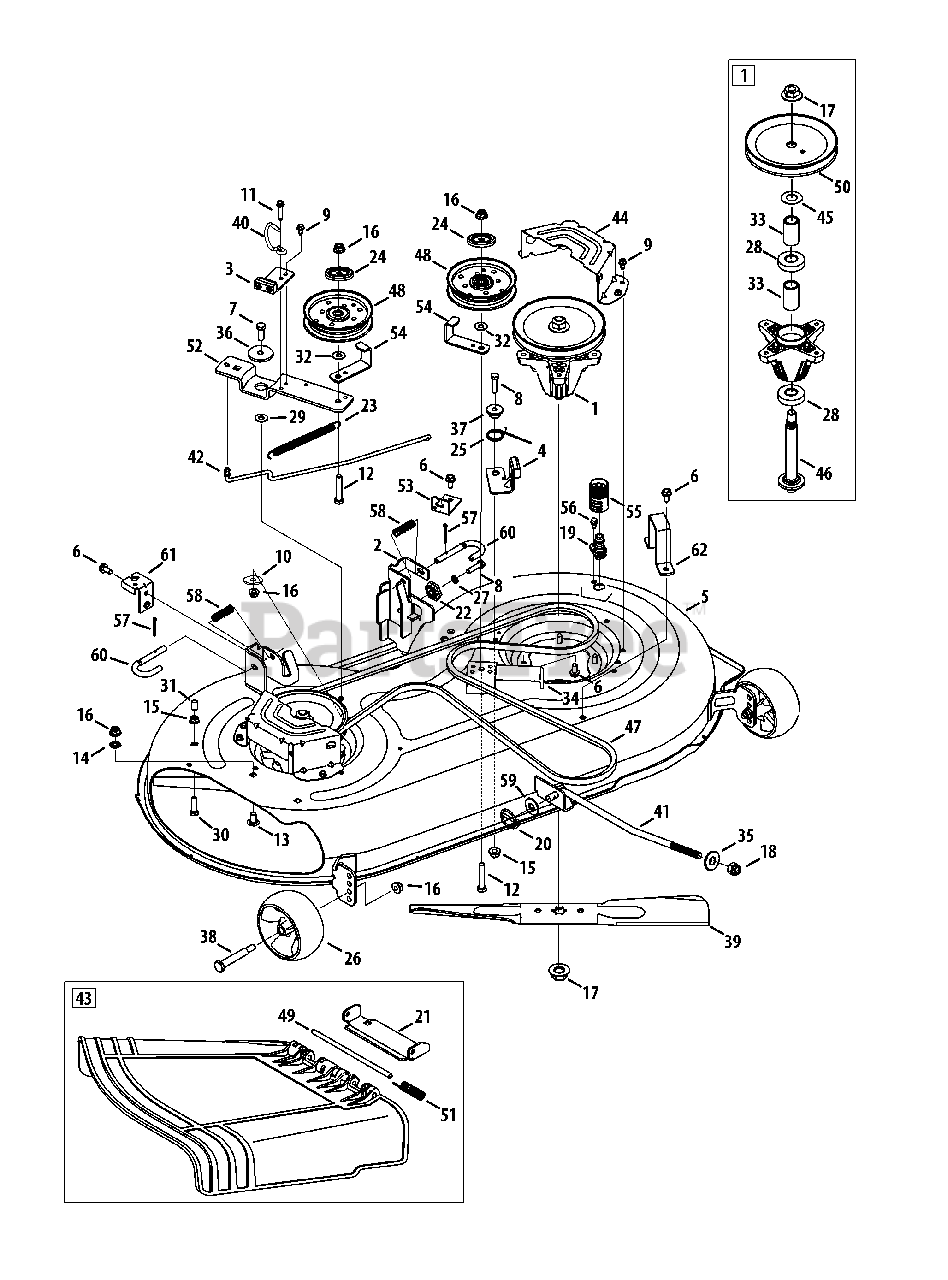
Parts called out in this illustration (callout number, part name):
1	Spindle Ass’y, Pulley, 6.3 Dia
2	Bracket Ass’y, Deck, Hanger LH
3	Brake Ass’y, Deck, 42/46
4	Brake Ass’y, Deck
5	Deck Ass’y, Offset, 42" W/O wheel
6	Screw, Self-tapping, 5/16-18, .750
7	Hex Screw, 3/8-16, 1.25, Gr5, Std
8	Hex Screw, 5/16-18, 1.25, Gr5, Std
9	Screw, Self-tapping, 1/4-20, 0.500
10	Flat Washer, .406 x 1.500 x .105
11	Screw, Self-tapping, 1/4-20, .750
12	Hex Screw, 3/8-16, 2.00, Gr5, Std
13	Bolt, Carriage, 3/8-16, 0.75, Gr1
14	Nut, Push, 3/8
15	Nut, Flange Lock, 5/16-18, Grf
16	Nut, Flange Lock, 3/8-16, Grf
17	Nut, Flange, 5/8-18
18	Nut, Lock, 1/2-13
19	Deck Wash Nozzle
20	Lynch Pin, .1875
21	Chute Bracket
22	Gear, Deck, Adjustment
23	Spring, Extension, .62 Dia x 6.12
24	Pulley Cap
25	Spring, Torsion, .992 ID X 1.17 OD
26	Wheel, Deck, 5.0 Dia Ball
27	Washer, Lock, 5/16, Regular Duty
28	Bearing, Ball, .787id x 1.85 Odx.551
29	Washer, Flat, .385 X 1.0 X .030
30	Hex Cap Screw, 5/16-18 x 1.00
31	Cap, .290 x .500
32	Washer, Flat, .385 x .870 x .092
33	Spacer, .792 x 1.060 x 1.860
34	Bracket, Support, Stationary Idler
35	Bell Washer, .63 X 1.25 X .18
36	Spacer, Shoulder, .8840 x .190
37	Shoulder Spacer
38	Bolt, Shoulder, .496 x 2.50, 3/8-16
39	Blade, Cut, 21.23" 2-In-1
40	Rod, Keepr, Belt 42 Idler
41	Deck Lift Rod
42	Rod, Control, Brake 42"
43	Chute Assembly, 42" Deck
44	Deck Belt Cover, 42
45	Washer, Flat, .760 Idx1.50 OD
46	Shift, Spindle, 6.11.
47	Belt, V Type, A Sec X 96.5
48	Pulley, Idler, 4.25"Dia
49	Pin, Hinge, Dia .3125 x 7.96
50	Pulley, Deck, 6.3 Dia
51	Spring, Torsion, .44 I.D. X 2.0
52	Pivot idler Bracket
53	Bracket, Cable, Deck Engage
54	Bracket, Guard, Belt, 4.25 Pulley
55	Water Nozzle Adapter
56	Shoulder Screw, 1/4-20 x 0.50
57	Cotter Pin, 1/8 X 1.25
58	Comp. Spring, .535 OD X 1.751 LG
59	Flat Washer, .531 X 1.25 X .100
60	Deck Release Handle Rod
61	Deck Engage Cable Bracket
